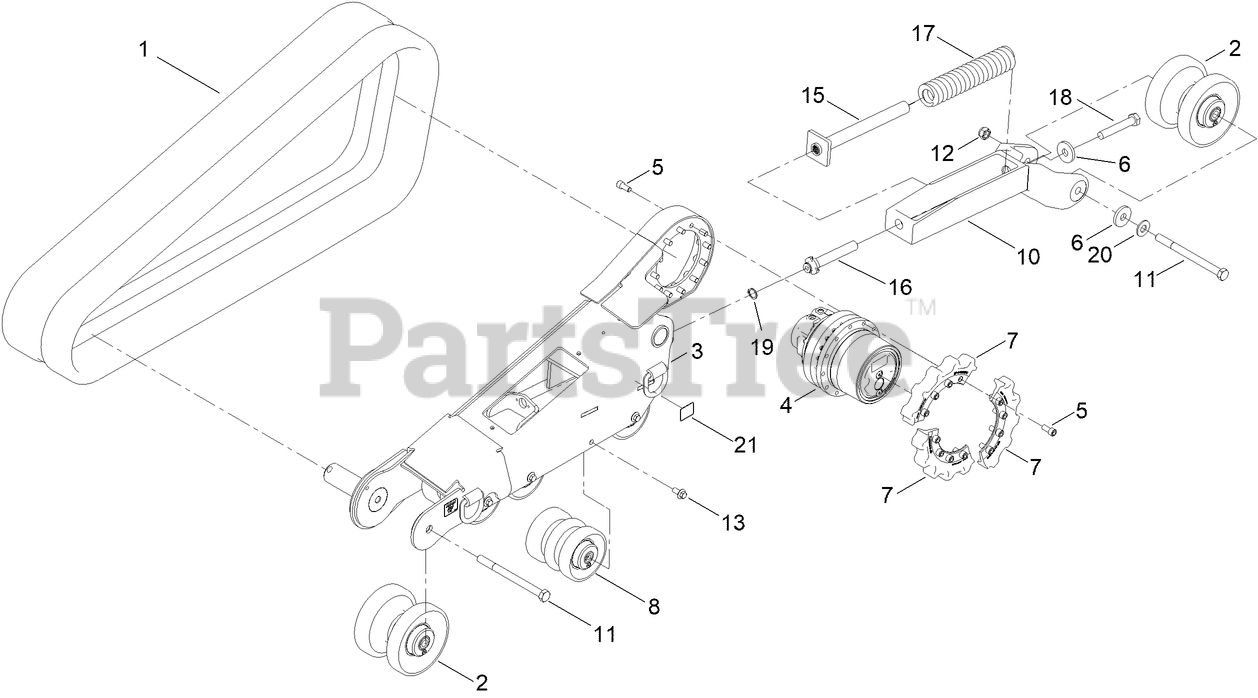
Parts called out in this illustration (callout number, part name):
1	TRACK
2	FRONT WHEEL ASM
3	LH TRACK MOUNT ASM
4	DRIVE-TRACK
5	SCREW-HSH
6	WASHER-WHEEL
7	SPROCKET-DRIVE
8	ROAD WHEEL ASM
10	TENSIONER ASM
11	BOLT-HH
12	NUT-HEX
13	SCREW-HHF
15	SPRING CATCH ASM
16	SCREW-TENSIONER
17	SPRING-COMPRESSION
18	BOLT-TAP
19	RING-RETAINING, EXTERNAL
20	WASHER-PLAIN
21	DECAL-TIE DOWN
